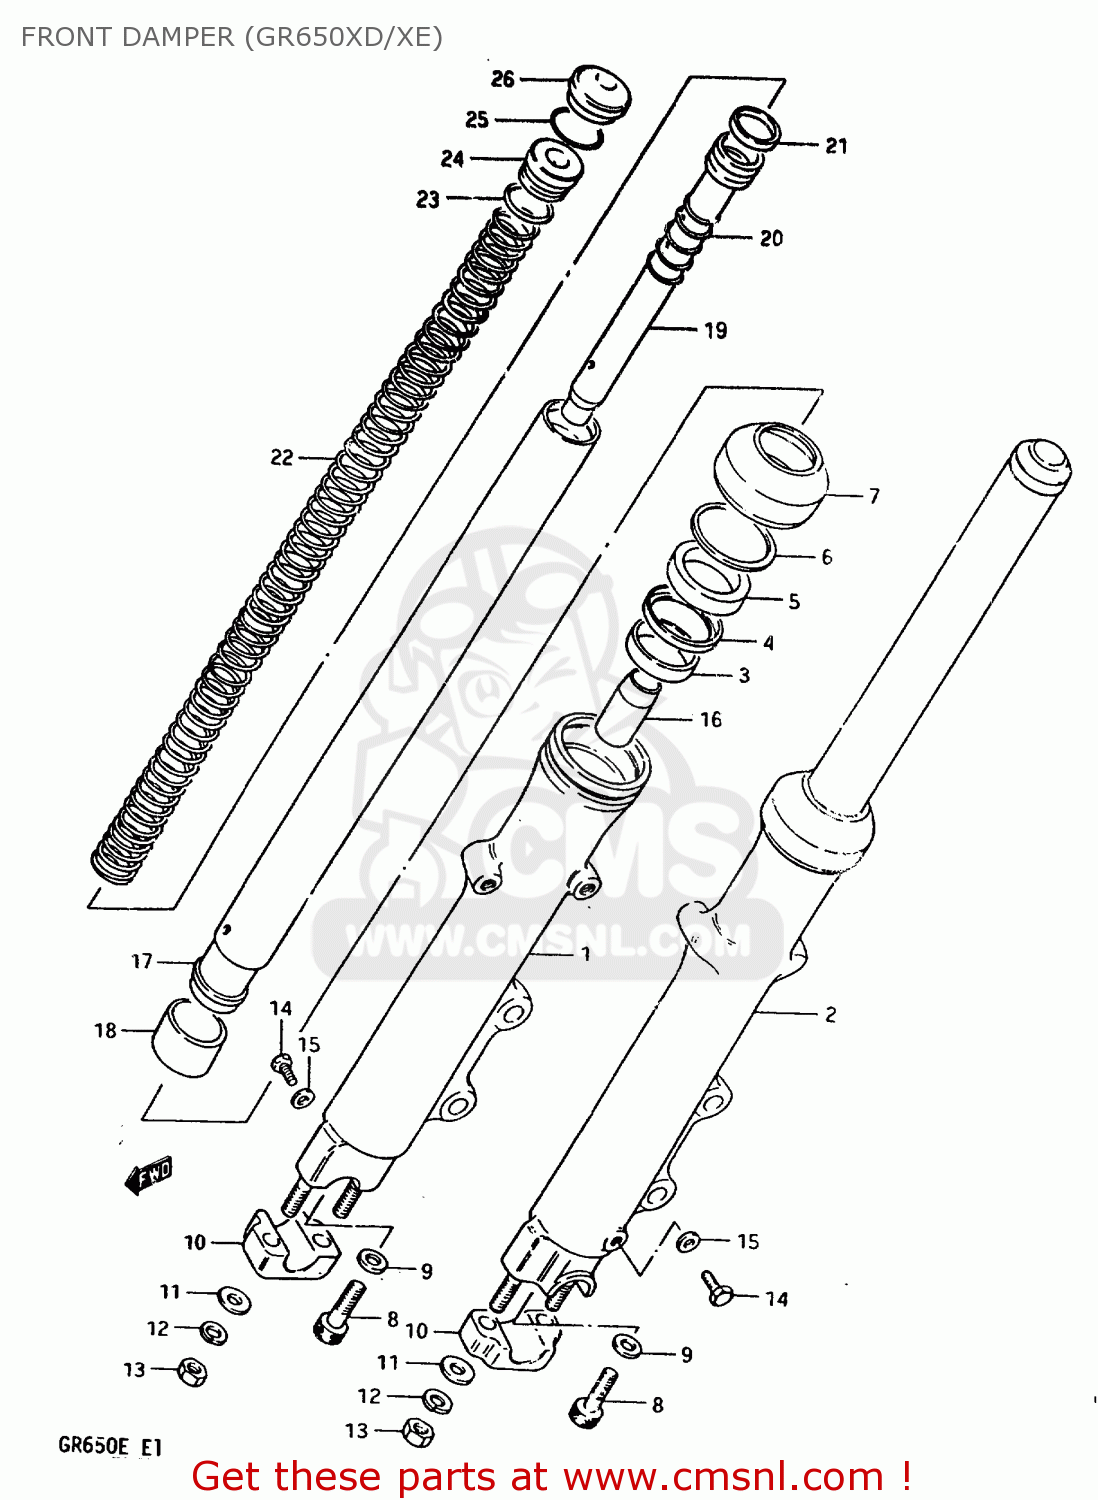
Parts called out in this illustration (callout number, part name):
1	TUBE,OUTER,RIGHT
2	TUBE,OUTER,LEFT
3	BUSHING,GUIDE
4	SPACER,SEAL
5	OIL SEAL,FRONT FORK
6	CIRCLIP,FORK OIL SEAL
7	BOOT
8	BOLT(8X27)
9	GASKET (NAS)
10	HOLDER,AXLE
11	WASHER
12	LOCK WASHER
13	NUT (8MM)
14	BOLT
15	GASKET,DRAIN,PLUG (NAS)
16	PIECE,OIL LOCK
17	TUBE,INNER
18	PISTON
19	CYLINDER
20	SPRING,REBOUND
21	RING,FRONT FORK PISTON
22	SPRING
23	O-RING
24	GUIDE,FRONT FORK SPRING
25	RING,STOPPER
26	CAP
